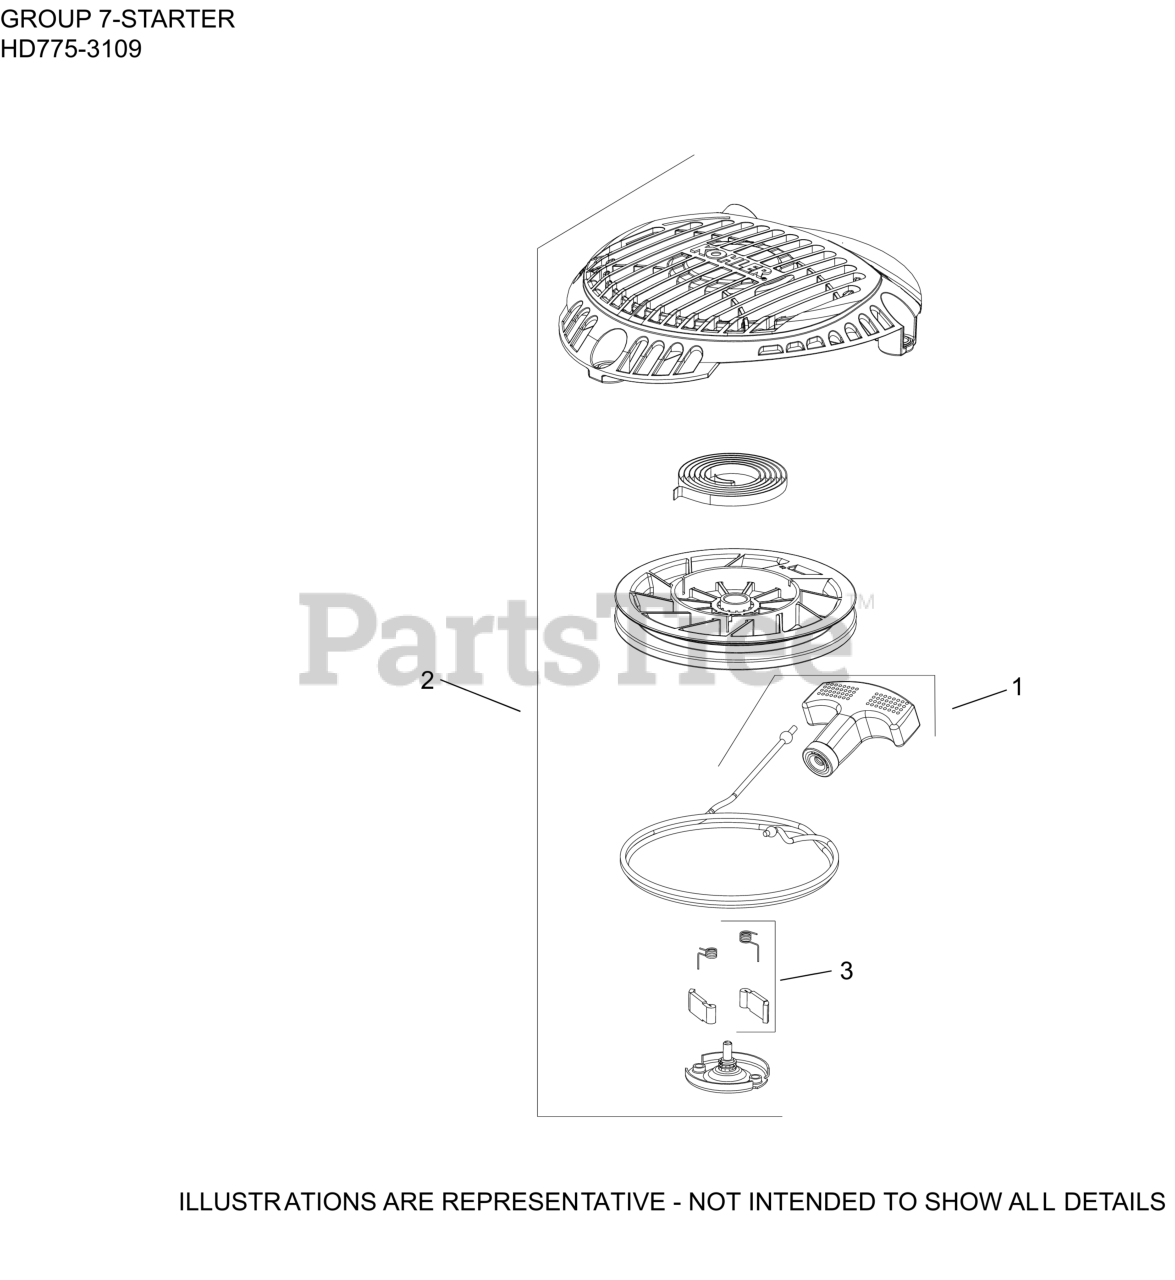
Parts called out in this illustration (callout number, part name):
1	KIT, STARTER ROPE W/HANDLE
2	STARTER ASSEMBLY, RETRACT
3	KIT, PAWL REPAIR
